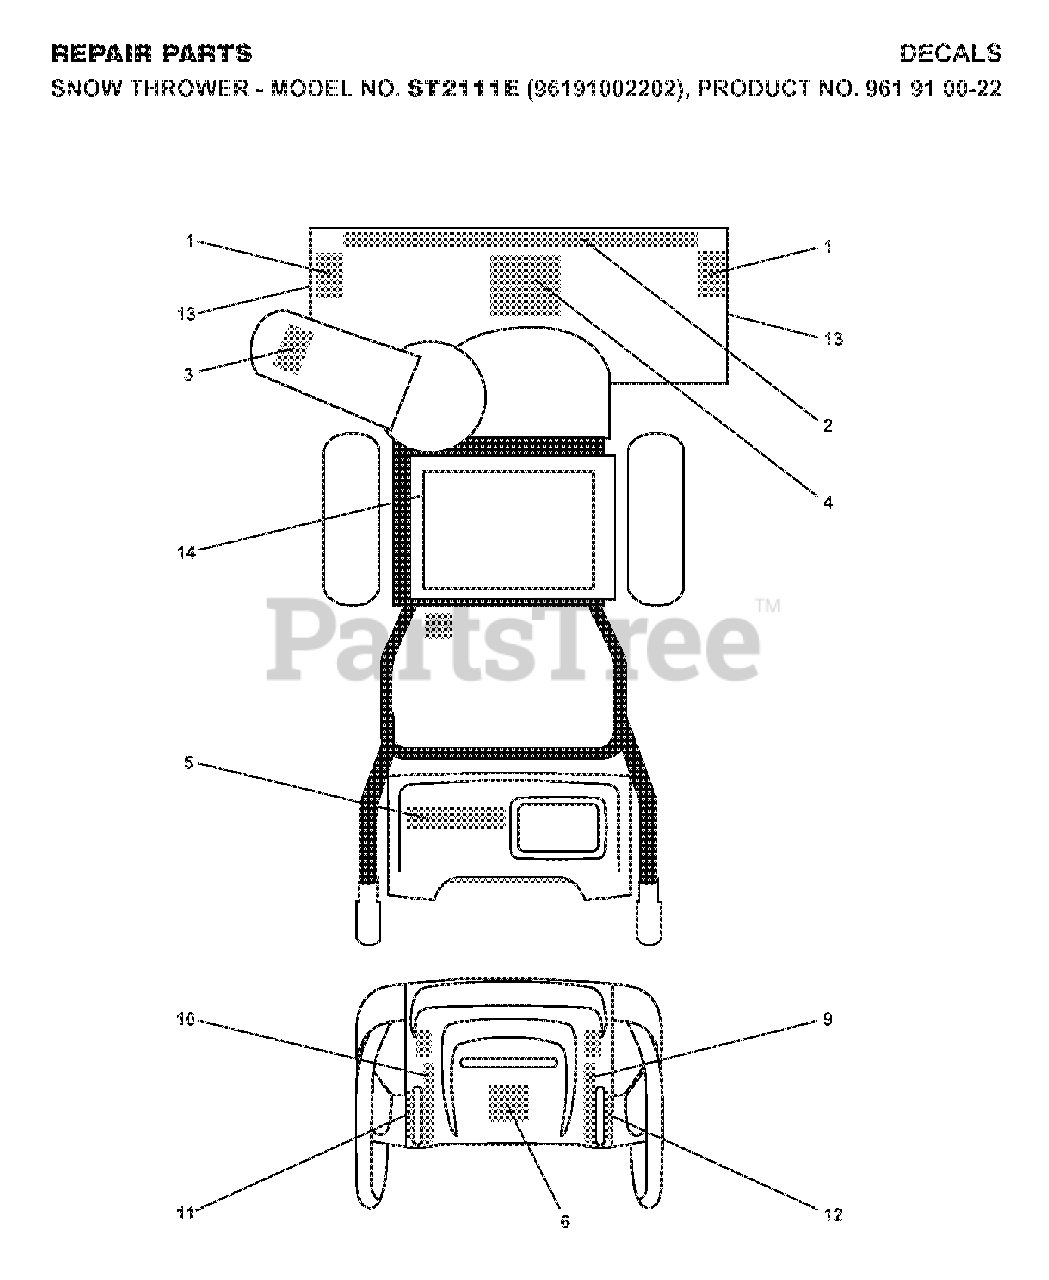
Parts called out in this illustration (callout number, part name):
1	DECAL.AUGER.SAFETY.
3	DECAL.CHUTE.SAFETY.
4	DECAL.AUGER."
6	DECAL.CONSOLE.INSTRUCTION
10	DECAL.REM.DEFLECTOR.LT
11	DECAL.POWER.STEER.LT.TRIG.INT
12	DECAL.POWER.STEER.RT.TRIG.INT
14	DECAL.BELT.GUARD.
